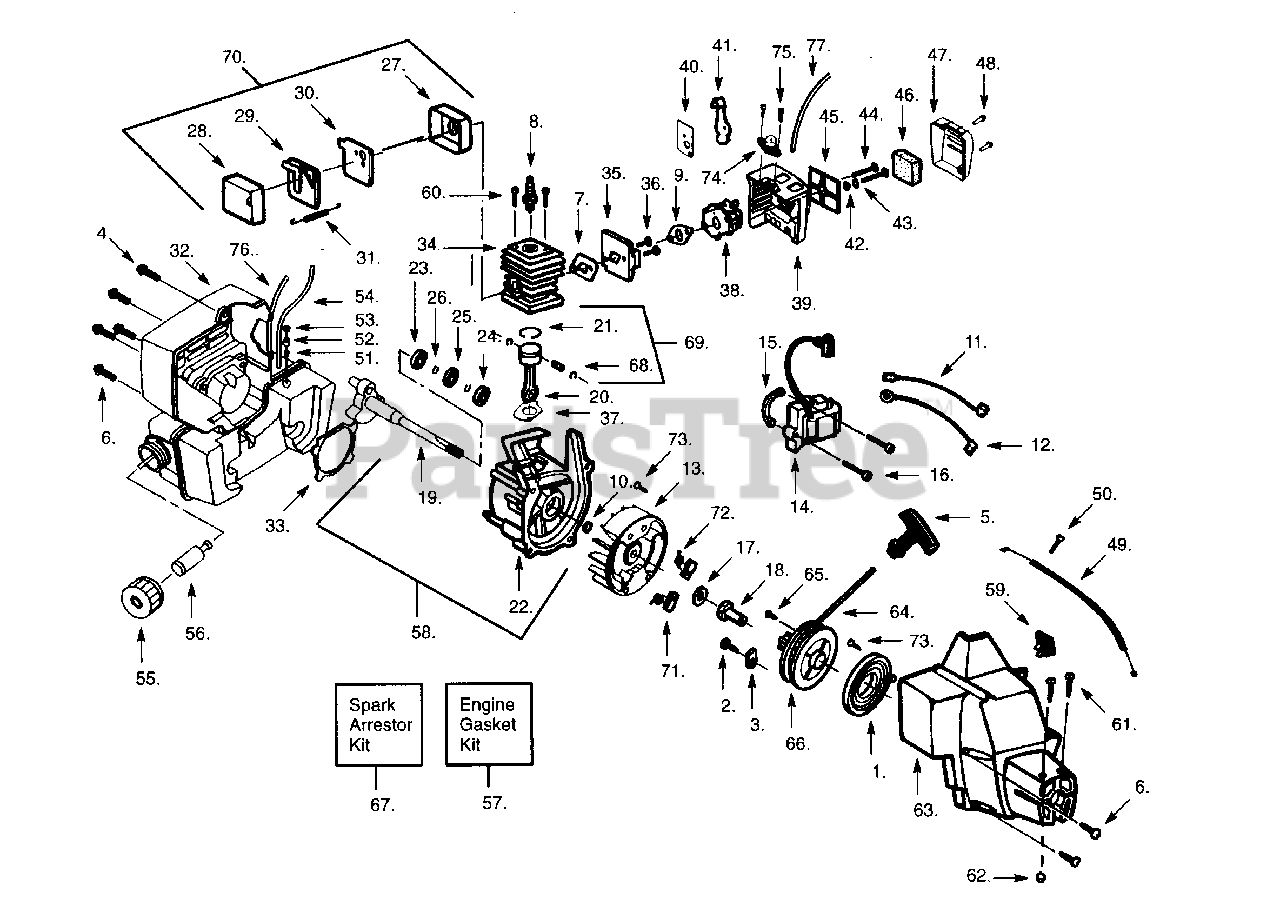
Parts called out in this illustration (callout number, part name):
1	Starter Spring
2	Screw-Pulley
3	Retainer
4	Screw-Fan Hsg./Shroud
5	Starter Handle
6	Screw-Shroud
7	Cylinder/Carb. Gasket
8	Spark Plug (RCJ-8Y)
9	Gasket-Carburetor
10	RetainerRing-C'case
11	Lead Wire
12	Ground Wire
13	Flywheel
14	Ignition Module
15	Spacer-Ignit. Module
16	Screw-Ignit.Module
17	Washer-Thrust
18	Drive Coupling
19	Crankshaft Ass'y.
20	Connecting Rod Ass'y.
21	Piston Ring
22	Crankcase Ass'y. (Incl. 23-26)
23	Inner Bearing
24	Outer Bearing
25	C'case Seal
26	Retainer-Crankshaft
27	Muffler Body
28	Muffler Cover
29	Muffler Baffle-Exit
30	Muffler Baffle-First
31	Muffler Spring
32	Shroud & Tank Assy.
33	Gasket-C'case
34	Cylinder Kit
35	Carb. Adaptor Kit
36	Screw-Carb. Adaptor
37	Gasket-Cylinder
38	Carburetor Kit (WT218) w/Limiter Cap
40	Choke Plate
41	Choke Shutter
42	Wave Washer
43	Choke Spacer
44	Screw-Carburetor
45	Filter Plate
46	Air Filter Foam
47	Air Filter Cover
48	Screw-Air Box
49	Throttle Cable Ass'y.
50	Screw-Throttle Cable
51	Check Valve
53	Retainer
54	Fuel Line-Carb/Tank.
55	Fuel Cap Ass'y.
56	Fuel Pickup Ass'y.
57	Engine Gasket Kit (Incl. 7,9,33,37)
58	C'case & C'shaft Assy. (Incl. 10, 19,22-26)
59	On/Off Switch
60	Screw-Cylinder
61	Screw-Pinch Clamp
62	Locknut-Clamp
63	Fan Housing
64	Rope Kit
65	Screw-Rope Retain.
66	Starter Pulley
67	Spark Arrestor Kit
68	Piston Pin Retainer
69	Piston Kit (Incl. 21,68 & Pin)
70	Muffler Kit
71	Starter Dog
72	Starter Spring
73	Screw-Starter Spg.
74	Primer Bulb Ass'y.
75	Screw-Primer Bulb
76	Fuel Line-Prim./Tnk
77	Fuel Line-Carb/Prim
